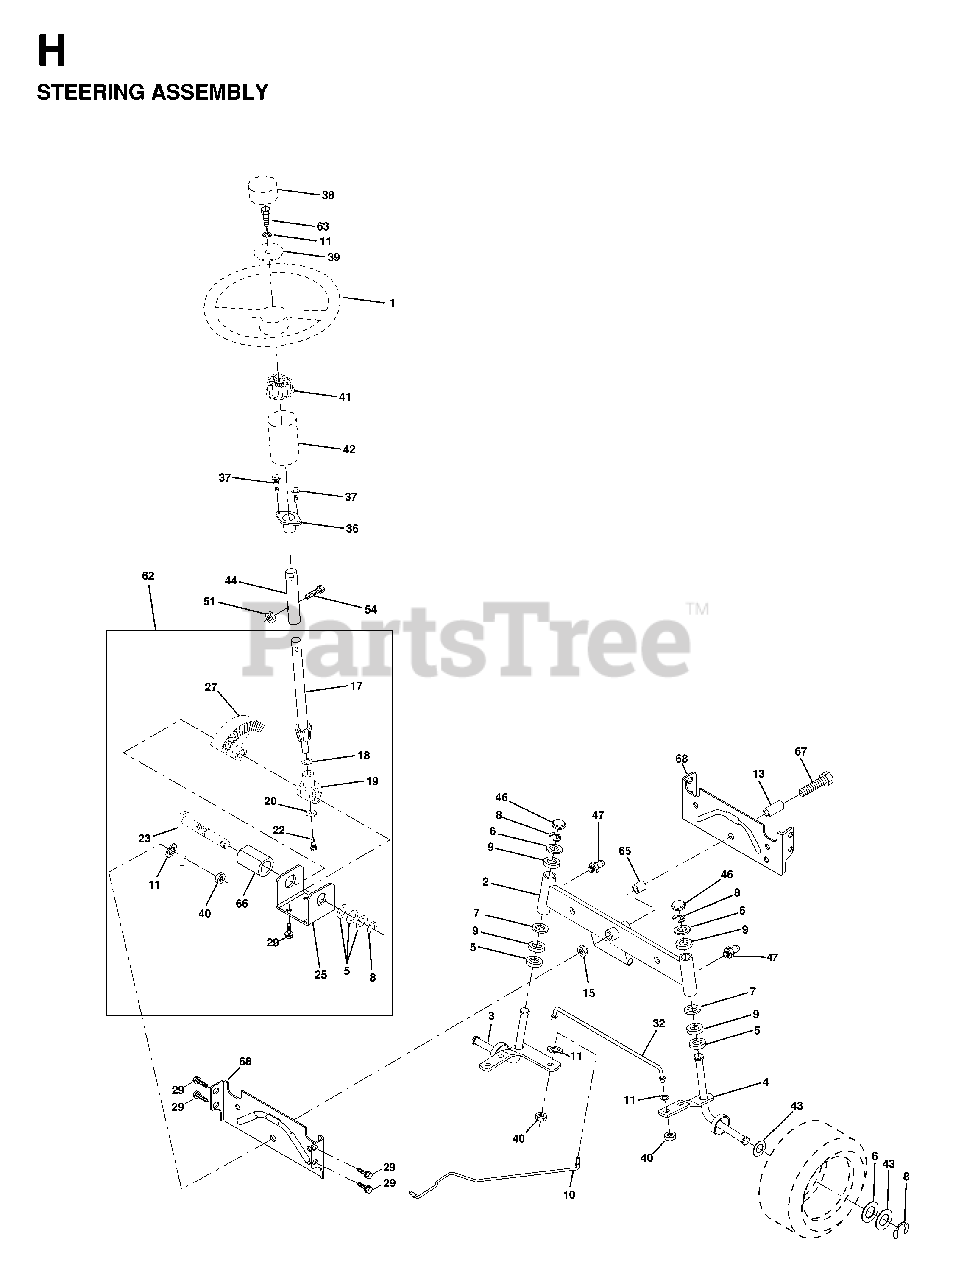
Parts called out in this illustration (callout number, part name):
2	FRONT AXLE ASSY
3	SPINDLE ASM LH
4	SPINDLE ASM RH
8	RING CLIP
9	BRNG T
10	LINK.DRAG.DROPPED.LT
11	WASHER, LOCK 3/8
13	BEARING AXLE
15	NUT-LOC,FLANGE LT
17	SHAFT ASM STEERING
18	THRUST WASHER
19	SHAFT,SUPPORT
20	WASHER
22	SCREW HEX SOCKET 1/4-20 X 5/8
23	SHAFT PITMAN
25	BRACKET STEERING
27	GEAR.SECTOR
29	SCREW
32	ROD ASSY/TIE BALL
36	BUSHING, STEERING
38	RP INSERT
39	WASHER T
40	GRIPCO NUT
41	ADAPTER LT
42	STEERING BOOT, GRAY
44	EXT SHAFT STEERING
46	CAP.SPINDLE
47	ZERK M
51	NUT.71038.31-18.HEX.NYLOCK
54	BOLT.5/16-18X1-1/4 FULL.THREAD
62	KIT, STEERING ASSEMBLY
65	SPACER AXLE
66	BEARING ARM
67	BOLT.HEX.FINISHED.5/8
68	AXLE, BRACE
